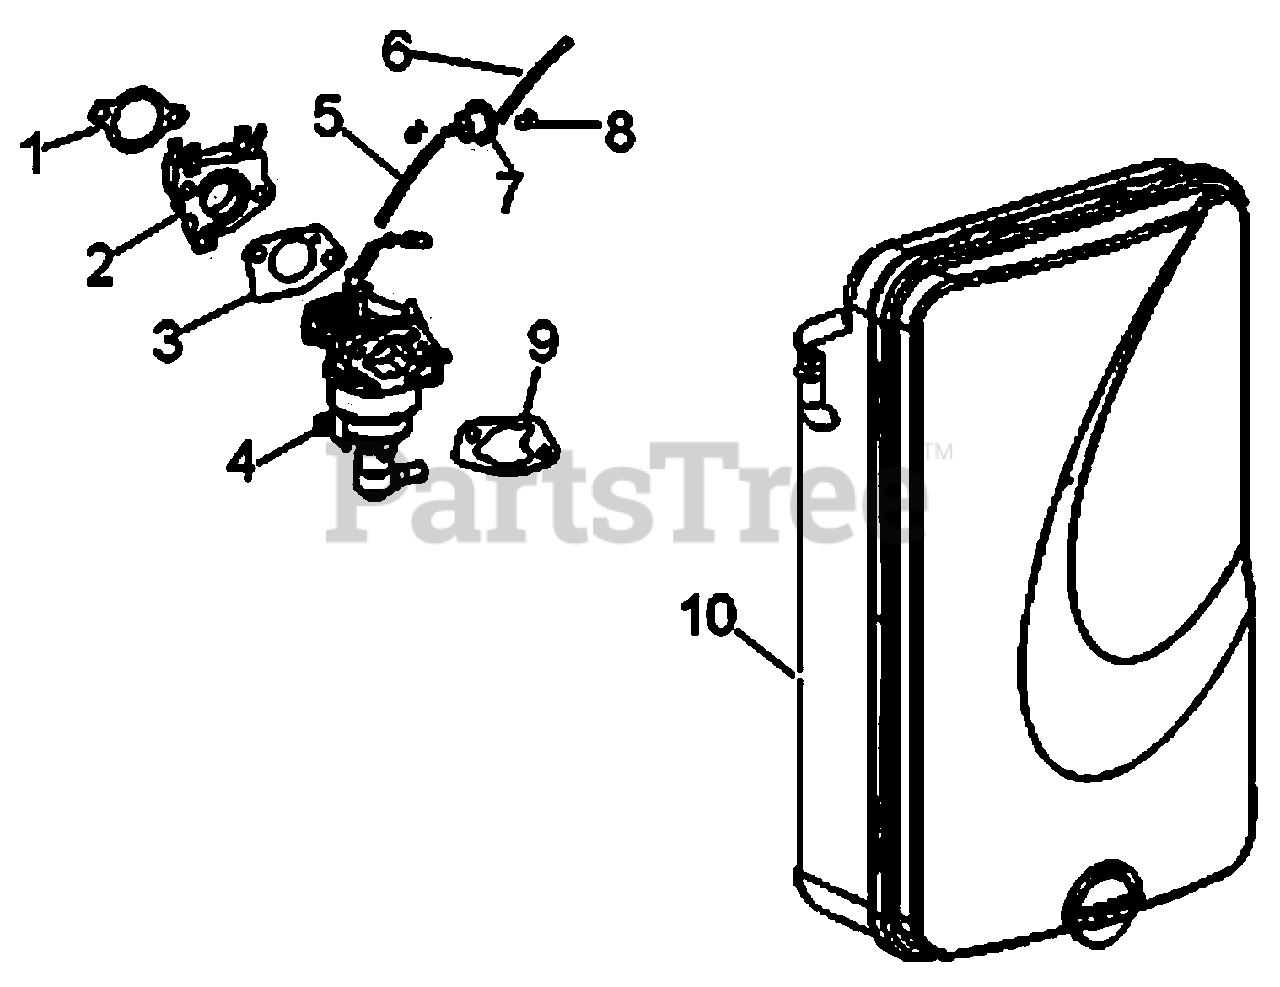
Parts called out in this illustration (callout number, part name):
1	GASKET, CARBURETOR
2	SPACER, CARBURETOR
3	GASKET, CARBURETOR
4	CARBURETOR ASSY.
5	TUBE, FUEL
6	TUBE, FUEL
9	GASKET, CARBURETOR
10	AIR CLEANER
